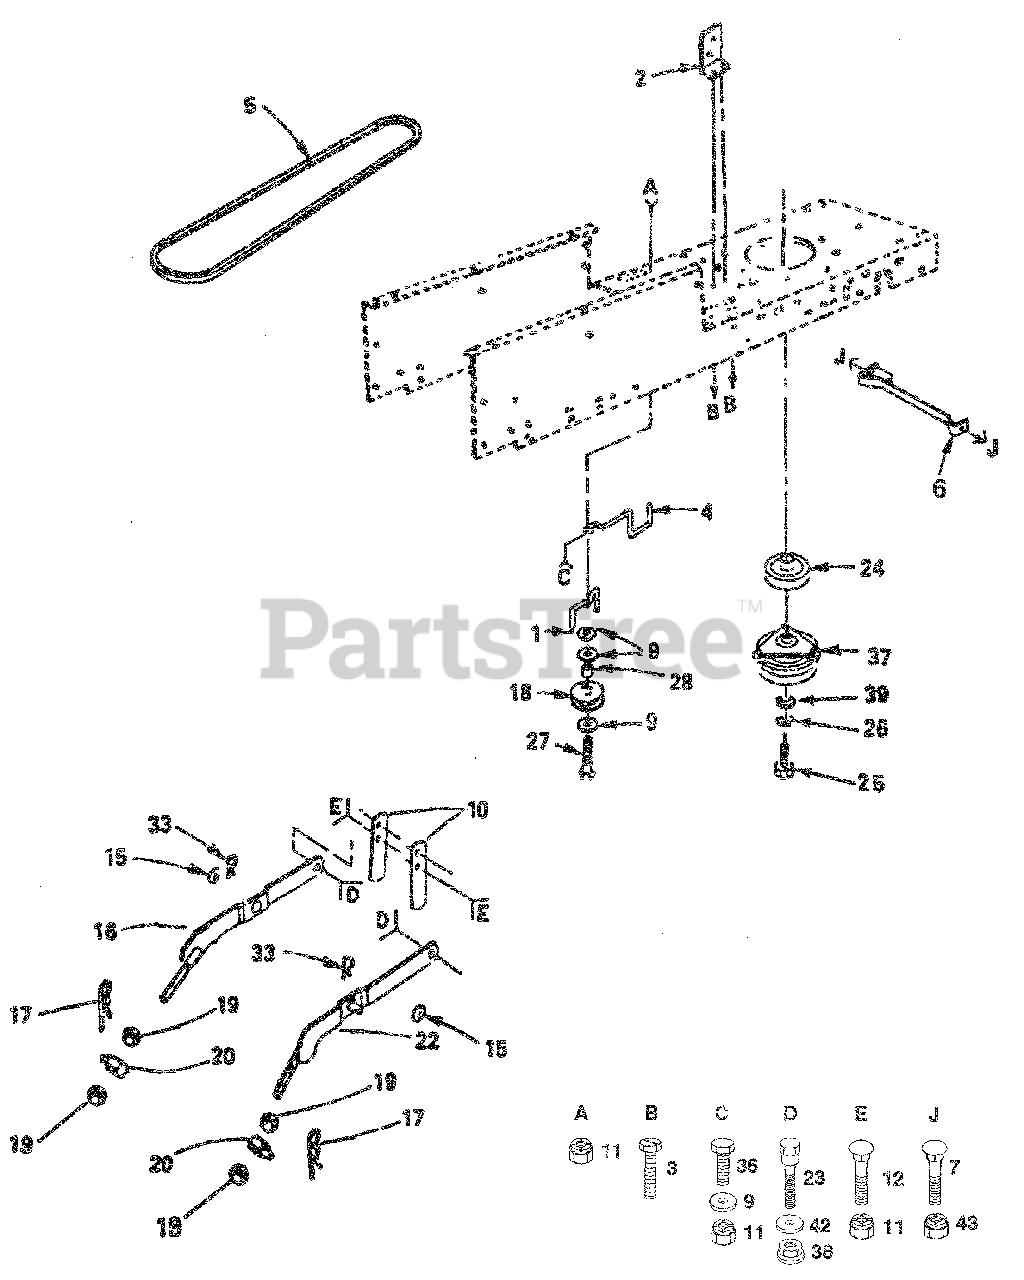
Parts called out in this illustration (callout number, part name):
1	Retainer, Belt
2	Bracket, Switch
3	Screw, Tapping, Hex #10-24 x 1/2
4	Keeper Belt Engine
5	V-Belt, Drive
6	Retainer Asm., Clutch
7	Bolt, Rdhd Sqnk 5/16 -18 x 3/4
9	Washer 13/32 x 13/18 x 12 Guage
10	Upstop, Mower
11	Nut, Crownlock 3/8-16
12	Bolt, Carriage 3/8-16 x 1
15	Washer 17/32 x 15 x 16 x 16 Gauge
17	Retainer, Spring
18	Arm Assembly, Suspension, LH
18	Idler, Flat
19	Nut, Hex 1/2-13
20	Trunnion, Lift, Lower
22	Arm Assembly, Suspension, RH
23	Bolt, Shoulder 3/8-16
24	Pulley, Engine
25	Bolt, Hex, Fin 7/16-20 UNF x 4-1/4 Grade 8
26	Washer, Lock 7/16
27	Bolt, Hex 3/8-16 x 2-3/4
28	Spacer
33	Spring, Retainer
36	Bolt, Hex 3/8-16 x 1
37	Clutch, Electric
38	Nut, Centerlock, Flange 3/8-16
39	Washer 1-1/2 x 15/32 x 1/4
42	Washer, Spring
43	Nut, Crownlock 5/16-18
